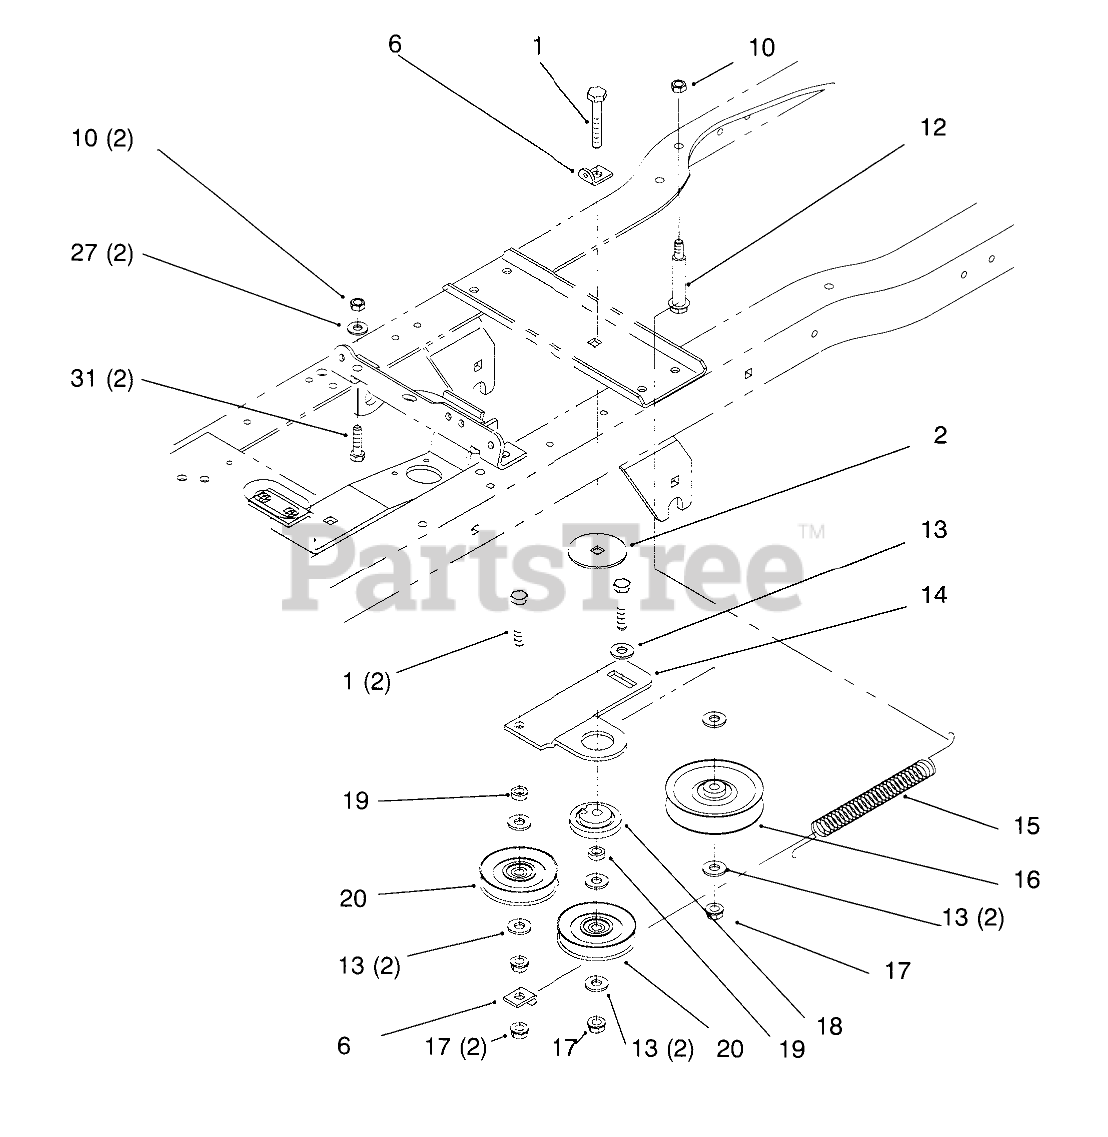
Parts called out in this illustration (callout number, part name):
1	SCREW-HH
2	WASHER-BEARING
6	CLIP - SPRING
10	NUT-LOCK, NI
12	BOLT-SHOULDER
13	WASHER-FLAT
14	ARM - IDLER
15	SPRING - CLUTCH
16	PULLEY-IDLER, FLAT
17	NUT-LOCK, NI
18	BUSHING
19	Spacer
20	PULLEY-IDLER
27	WASHER-PLAIN
31	SCREW-HH
